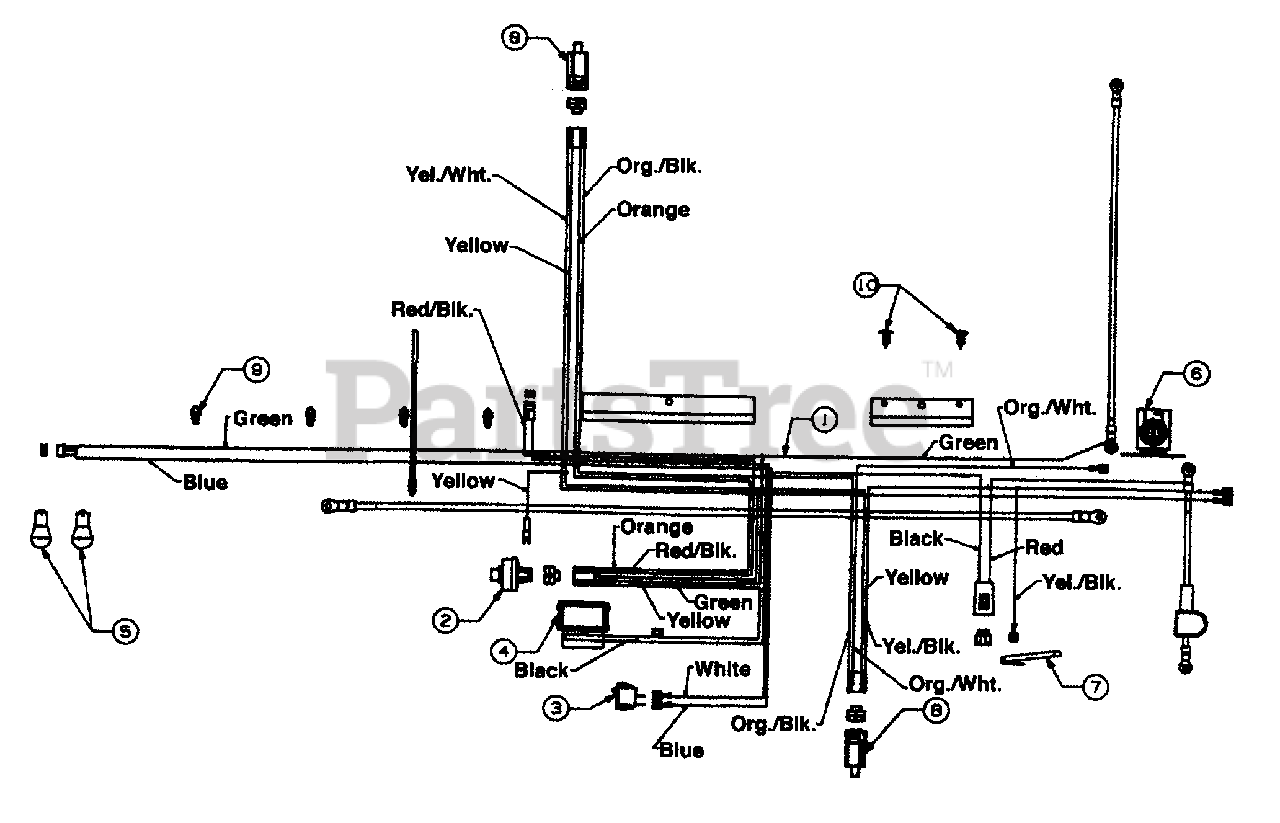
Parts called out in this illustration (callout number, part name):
1	Wire Harness w/Light Switch & Amp
2	Ignition Switch
3	Light Switch
4	Ammeter
5	Bulb (Headlight)
6	Solenoid
7	Safety Switch (Reverse)
8	Safety Switch
9	Wire Retainer Clip
10	Ratchet
